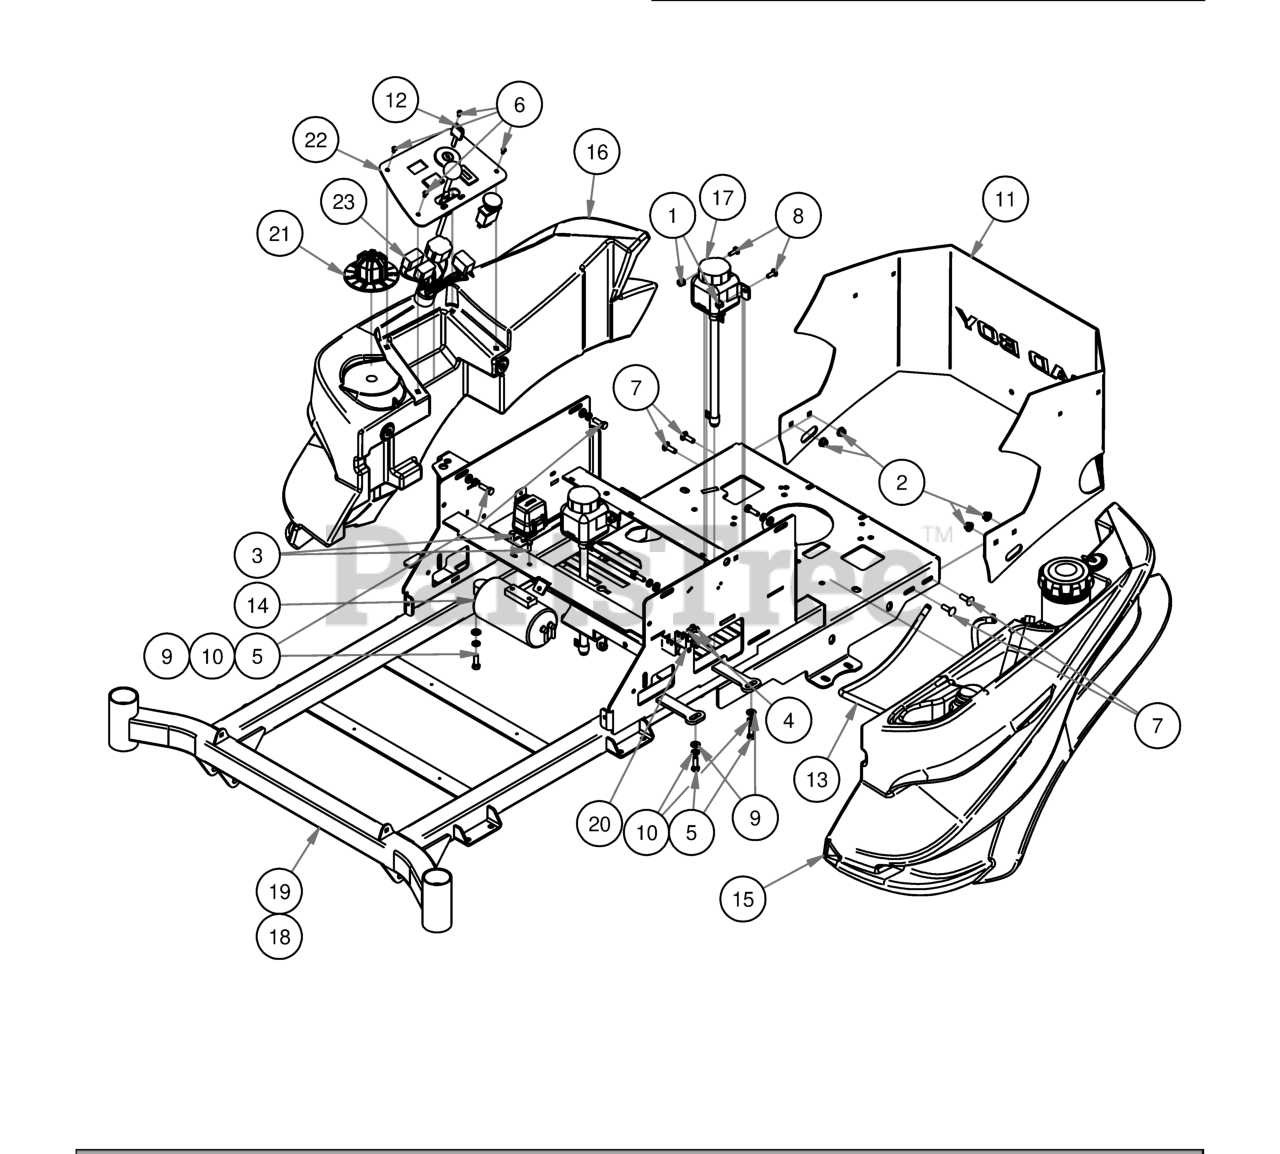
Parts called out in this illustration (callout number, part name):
1	1/4-20 Nylon Insert flange Nut
2	5/16" Nylock Flange Nut Zinc
3	M6-1.0 X 16MM Hex Bolt
4	12-24x 1/2 HWH Bolt
5	5/16" x 1" Bolt
6	10-32 x 3/8" Button Socket Head Bolt
7	5/16" x 1" Carriage Bolt
8	1/4" x 3/4" Carriage Bolt
9	5/16" Flat Washer
10	5/16" Lock Washer
11	2017 ZT Rear Plate
12	Ignition Key
13	37" Fuel Line Assembly
14	ZT/Mav EPA Cannister Assy
15	Left Fuel Tank
16	Right Side Console
17	Hydro Tank Assembly
18	ZT 54" and 60" Frame
19	ZT 48" Frame
20	Safety Switch
21	MZ/ZT Deck Height Dial
22	2017 Magnum Control Panel Assembly
23	Wiring Harness
131	Push Rod-Left
132	Deck Idler Spring
133	All Thread
